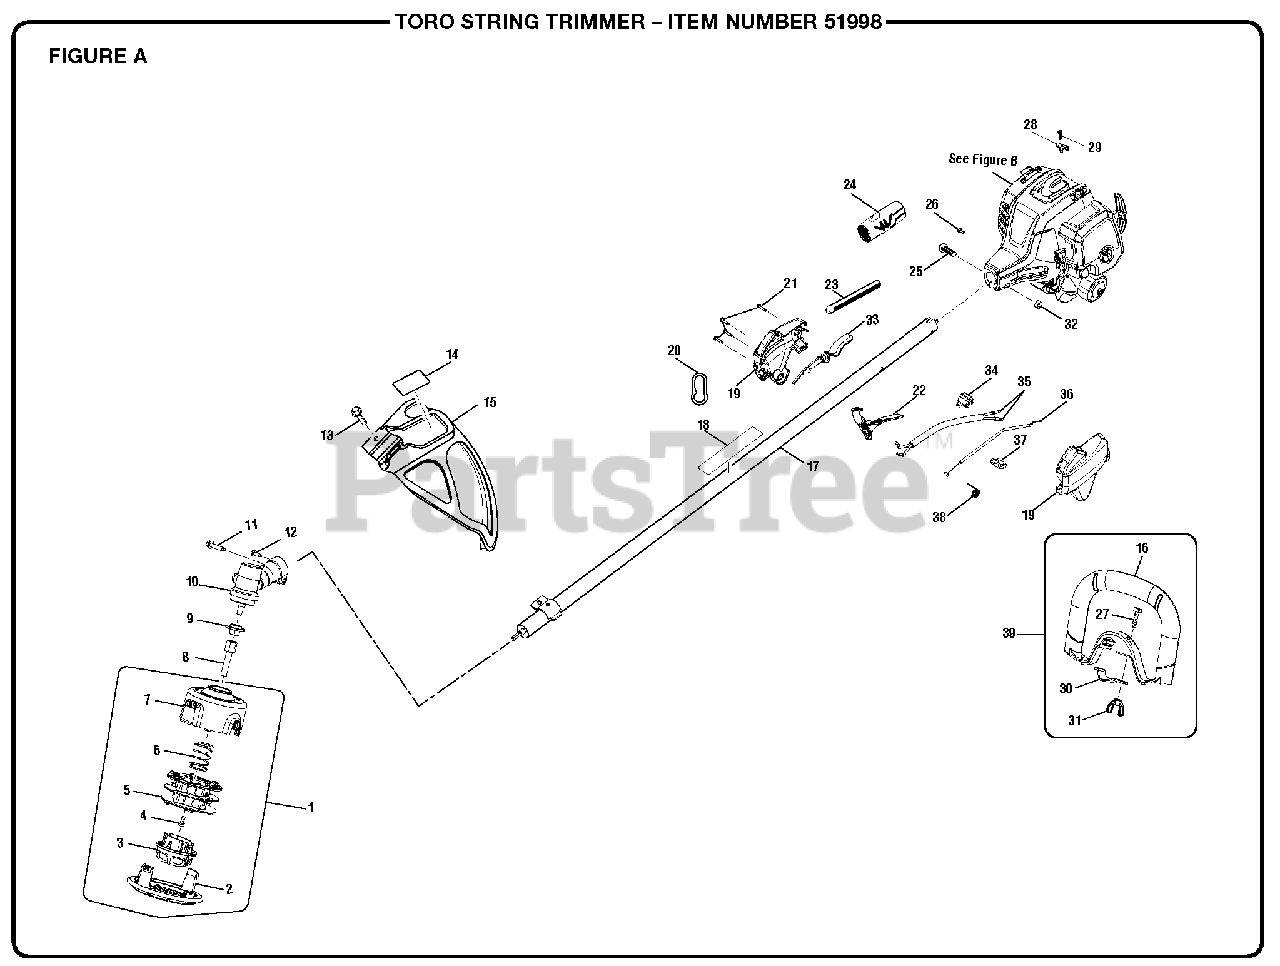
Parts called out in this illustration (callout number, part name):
1	Trimmer Head Assembly
2	Lower Stringhead Housing
3	Bump Knob
4	Bolt (5/16-18 x 1/2 in., L.H.)
5	Spool Assembly
6	Compression Spring
7	Main Stringhead Housing
8	Trimmer Head Shaft Adaptor
9	Flanged Washer
10	Gear Case Assembly
11	Screw (1/4-20 x 1-1/4 in., Hex Washer Hd. S.T.)
12	Screw (10-24 x 5/8 in., Hex Washer Hd. S.T.)
13	Screw (1/4-20 x 1-1/4 in., Hex Washer Hd.)
14	Grass Deflector Label
15	Grass Deflector Assembly
16	Front Handle w/Grip
17	Upper Boom Assembly
18	Warning Label
19	Control Handle Assembly
20	Shoulder Strap Clip
21	Screw (M4 x 20 mm, T20 Torx Pan Hd. S.T.)
23	Corrugated Tube (225 mm)
24	Rear Handle Grip
25	Screw (M6 x 30 mm, T27 Torx Button Hd.)
26	Screw (M4 x 8 mm, T20 Torx Pan Hd. S.T.)
27	Screw (1/4-20 x 1 in., Sq. Hd.)
28	Throttle Cable Clamp
29	Screw (M4 x 16 mm, T20 Torx Pan Hd. S.T.)
30	Front Handle Clamp
31	Wing Nut (1/4-20)
32	Hex Nut (M6 x 1)
33	Trigger Lock
34	On/Stop Switch
36	Throttle Cable
37	On/Stop Label
38	Trigger Spring.
39	Front Handle Assembly
